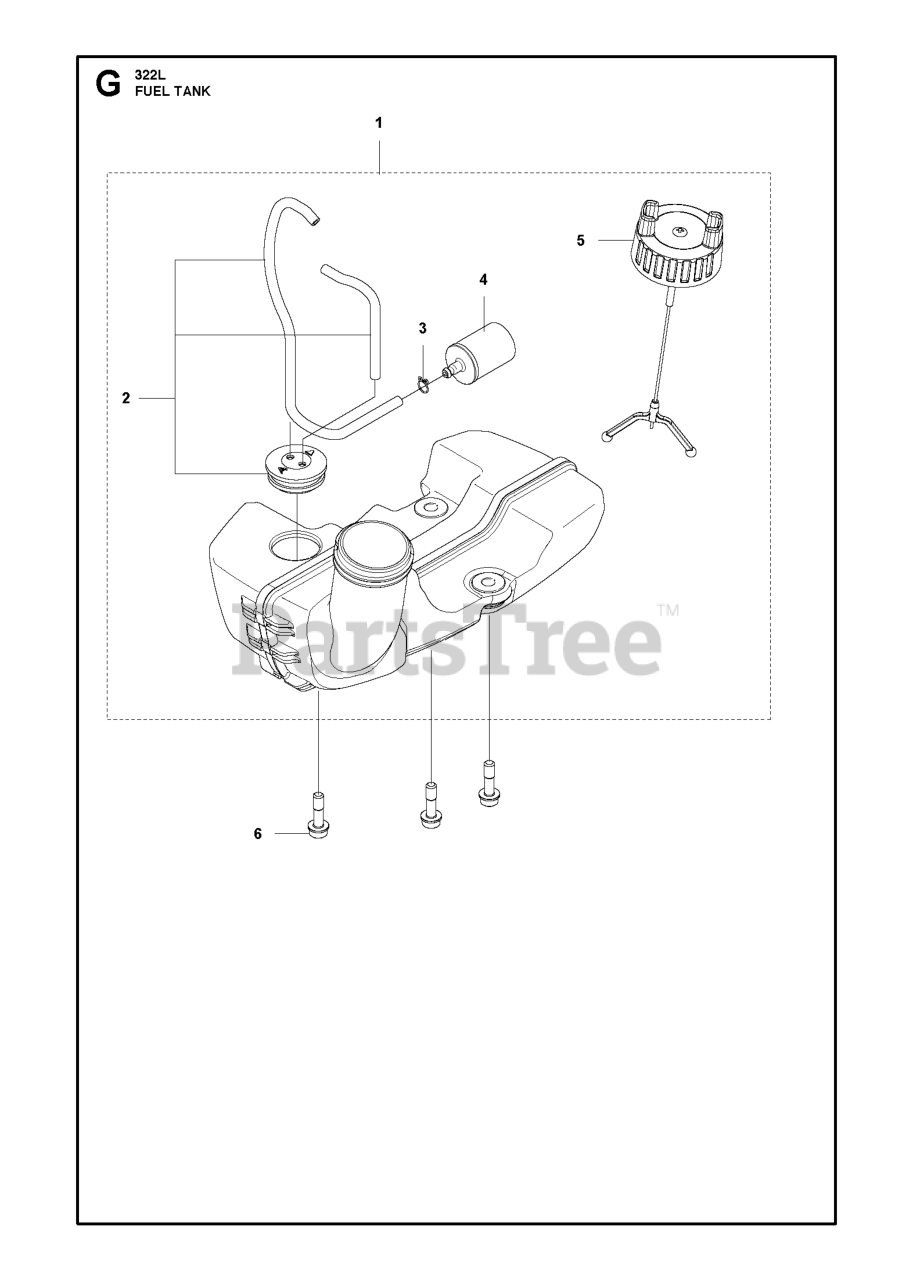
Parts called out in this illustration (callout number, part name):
2	FUEL HOSE ASSY
4	RP FUEL FILTER
6	BOLT
